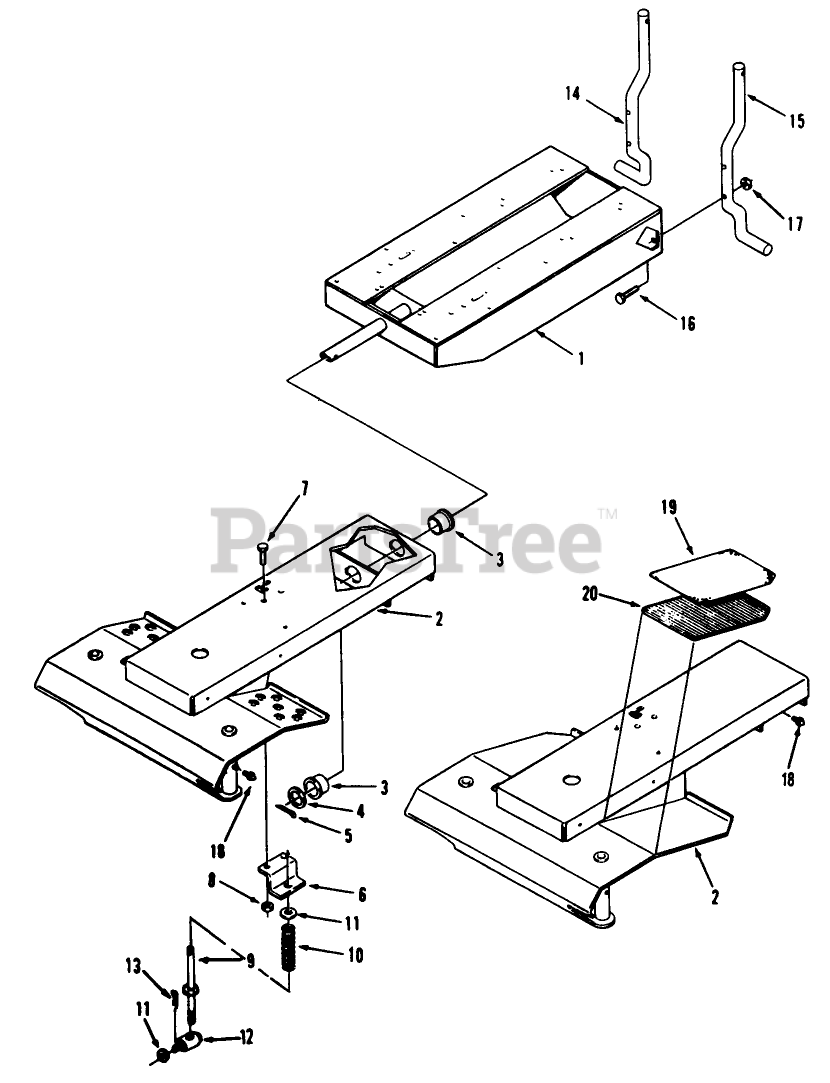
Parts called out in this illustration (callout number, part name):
1	ASS'Y-FRAME REAR *R
7	SCREW-HH
8	NUT-LOCK, NI
9	ASSY ROD
10	SPRING-COMPRESSION
11	WASHER-FLAT
13	PIN-COTTER
14	REAR ROD RH *B
15	REAR ROD LH *B
18	FITTING-GREASE
20	PAD FOOTREST RH
